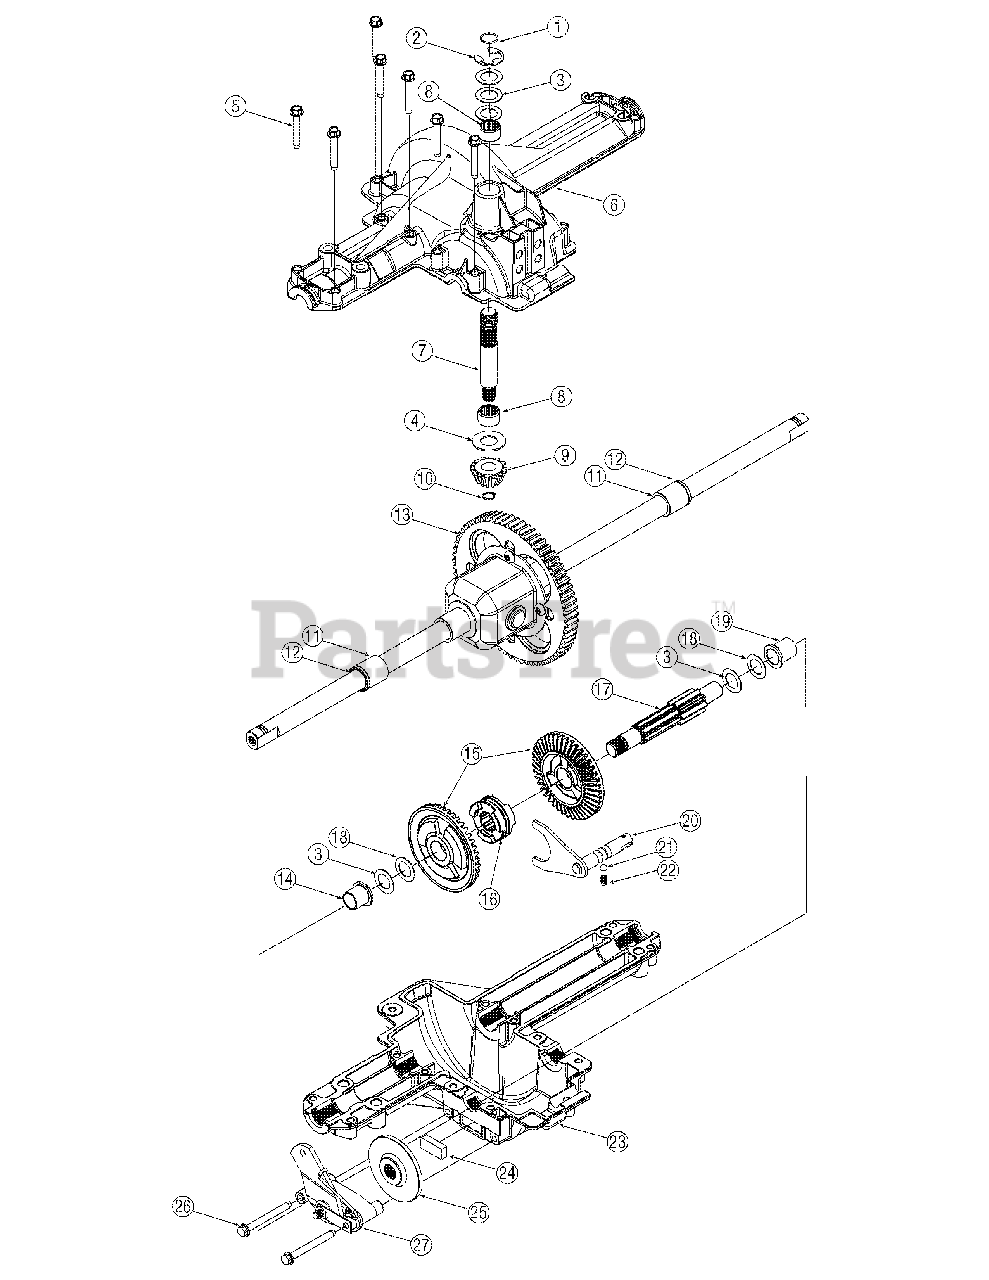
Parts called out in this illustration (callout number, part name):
1	Ring, Wire
2	Ring, E Type,.750
3	Flat Washer, 5/8 x 1.0 x.030
3	Flat Washer, 5/8 x 1.0 x.040
3	Flat Washer, 5/8 x 1.0 x.020
4	Washer, Thrust.635 x 1.26 x.06
5	Self-tapping Screw, 1/4-20 x 1.625
6	Upper Housing
7	Input Shaft
8	Needle Bearing,.625 x.813 x.495
9	14-tooth Bevel Pinion
10	Retaining Ring,.437
11	Sleeve Bearing,.75 x.1.0 x 1.0
12	Seal,.75 x 1.0 x.125
13	Differential Assembly
14	Flange Bearing, 5/8 x 3/4 x 3/4
15	42-tooth Bevel Gear
16	Clutch Collar
17	Drive Shaft
18	Thrust Washer, 1.0 x.632 x.0
18	Flat Washer,.632 x 1.00 x.035
19	Flange Bearing, 5/8 x 3/4 x 15/16
20	Detent Shaft Assembly
21	Detent Ball
22	Compression Spring
23	Lower Housing
24	Brake Puck
25	Brake Disc
26	Self-tapping Screw, 1/4-20 x 2.375
27	Brake Assembly
